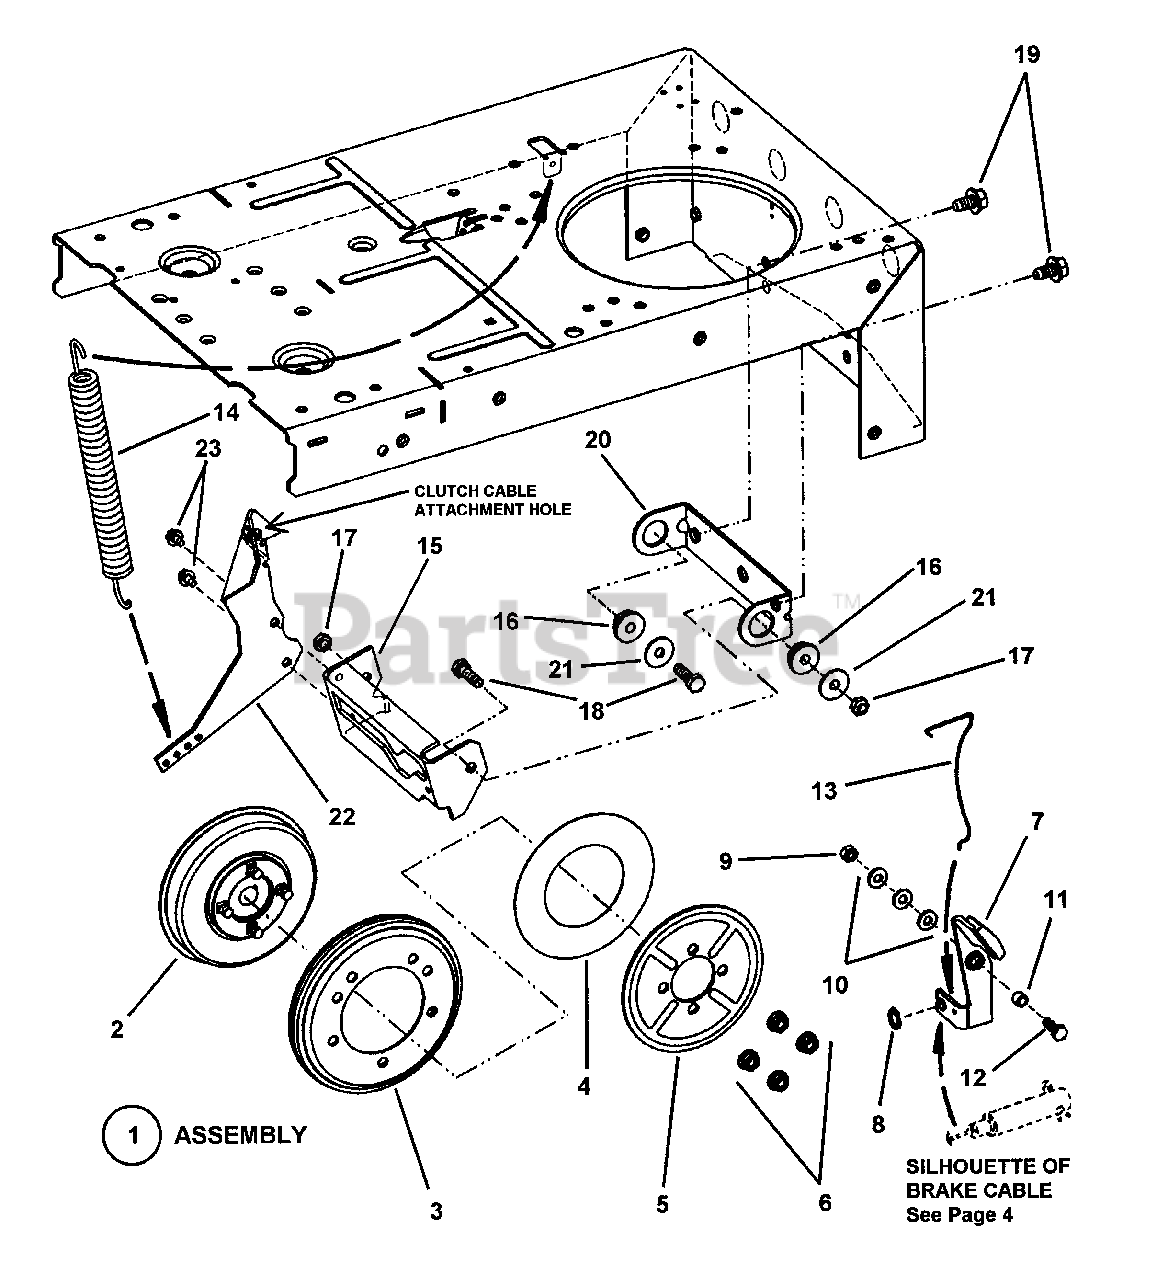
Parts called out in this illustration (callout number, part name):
1	ASSEMBLY, Smooth Clutch
2	ASSEMBLY, Driven Disc Hub
3	DISC, Driven
4	WASHER, Thrust
5	PLATE
6	NUT, 5/16-18 Hex Flange Lock
7	ASSEMBLY, Brake Lever
8	RING, 3/8" External Retaining
9	NUT, 1/4-28 Hex Top Lock
10	WASHER, 1/4" Flat
11	SPACER
12	SCREW, 1/4-28 x 1" Hex Head Cap, Grade 5
13	SPRING, Brake Return
14	SPRING, Clutch Brake
15	LIFT, Yoke
16	BEARING, Yoke
17	NUT, 5/16-24 Hex Center Lock
18	SCREW, 5/16-24 x 1" Hex Head Cap, Grade 5
19	SCREW, 3/8-16 x 5/8" Self-Tap
20	COLLAR, Yoke
21	WASHER, 5/16 Flat
22	ARM, Yoke
23	SCREW, 1/4-20 x 3/8" Self-Tap
